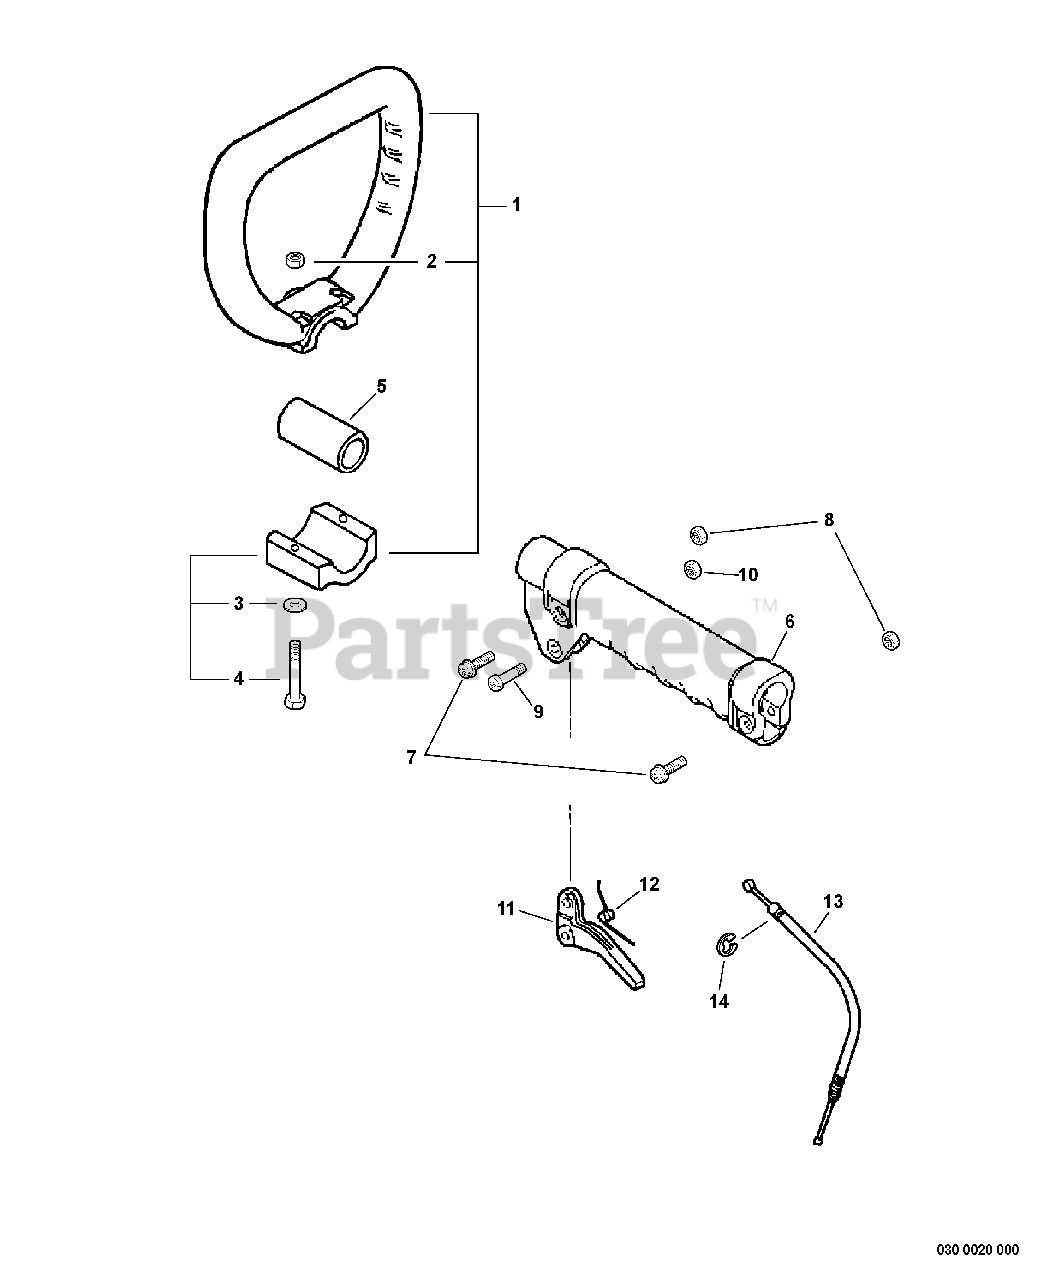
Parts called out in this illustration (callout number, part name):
1	LOOP HANDLE ASSY
3	WASHER - 5
4	SCREW - 5X40
6	GRIP, HANDLE
7	SCREW - 5X25
9	SCREW - 5X30
10	LOCKNUT - 5
11	TRIGGER, THROTTLE
12	SPRING, TRIGGER
13	CABLE, THROTTLE
14	RING, RETAINING - 5
